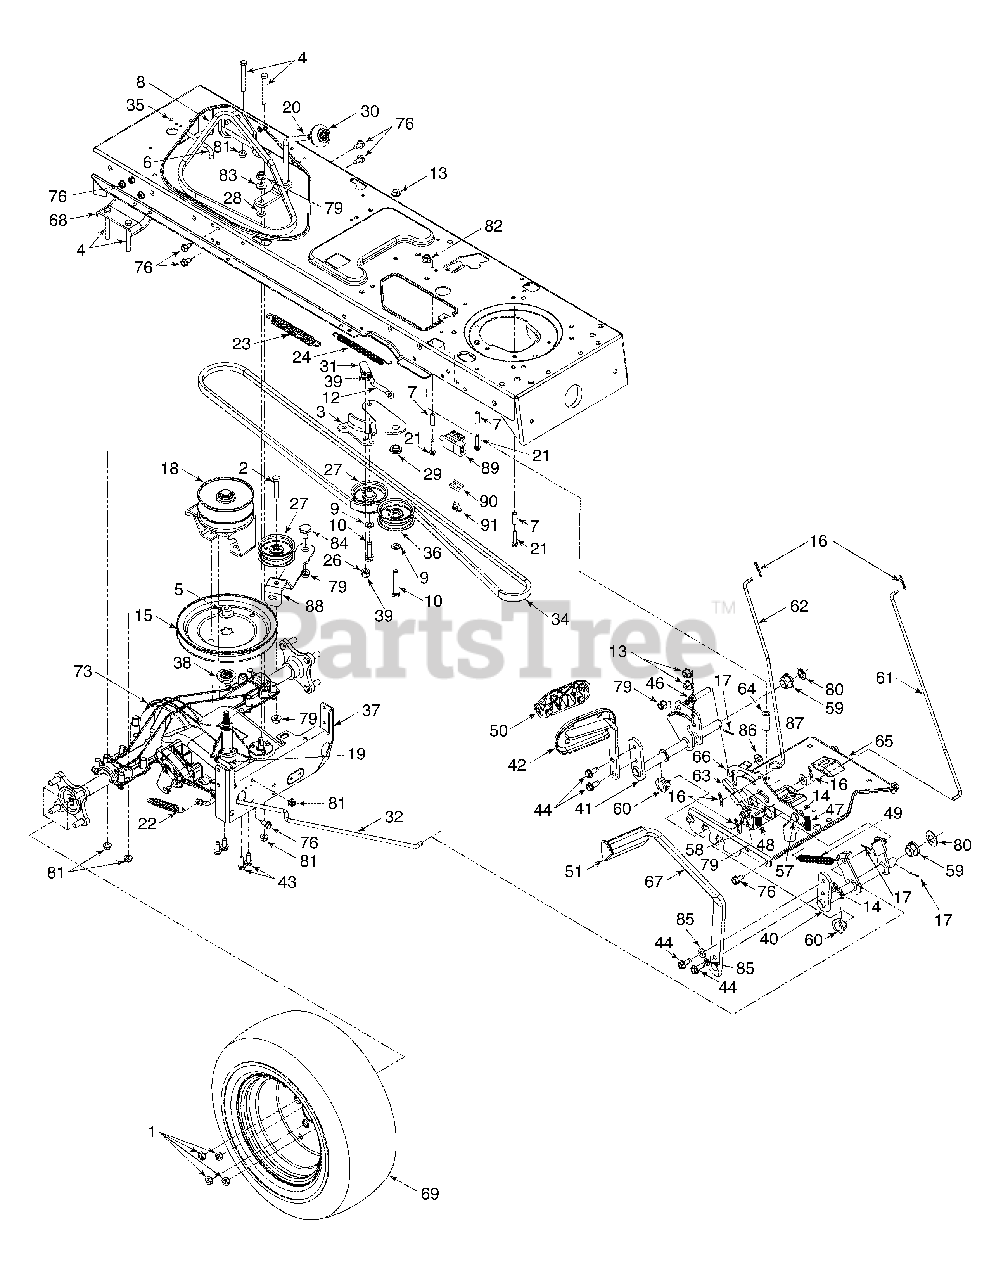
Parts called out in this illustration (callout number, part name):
1	Lug Nut, 7/16-14
2	Hex Screw 3/8-16 x 1.75
4	Hex Scr 5/16-18 x 2.75
5	Hex Flanged L-Nut 7/16-20 Gr. 2
6	Belt Guard Rod
7	Spacer .260 x .375 x 1.030 Lg.
8	Drive Belt
9	Flat Washer .40 ID x .812 OD x .135
10	Hex L-Wash HD Scr 3/8-16 x 1.5
12	Idler Adjustment Rod, 3/8
13	Hex. Flanged L-Nut 3/8-16 Gr. F
14	Hex Flange L-Nut 5/16-18
15	V-Pulley
16	Int. Cotter Pin .072 x 1.13" Lg.
17	Cotter Pin 3/32 dia x 1.00 Lg.
18	Variable Speed Pulley
19	Hex Bolt 5/16-18 x 1,50" Lg. Gr. 5
20	Shift Rod Assembly
21	Hex Bolt 1/4-20 x 1.25
22	Ext. Spring .59 OD x 4.00 Lg.
23	Extension Spring 6.12 Lg.
24	Extension Spring, .50 Dia. x 6.37
26	L-Wash 3/8 ID
27	Idler V-Pulley
28	Flat Washer .44 x .75 x .06
29	Shoulder Spacer
31	Drag Link Ball Joint
34	Variable-speed Belt
35	Thd Forming Scr. 1/4-20 x .75 Lg.
36	Flat Idler Pulley 2.75 OD
38	Pulley Hub 1/2 Spline
39	Hex Nut 3/8-24
43	Hex Wash Taptite 5/16-18 x .875
44	Hex Wash. Hd. Scr. 5/16-18 x .75 Lg.
46	Pin 3/8-16 x 2.68 Lg.
47	Compression Spring
48	Extension Spring, .50 OD x 1.41
49	Extension Spring, .50 Dia. x 6.37
50	AutoDrive Pedal Pad
51	Brake Pedal Pad
57	Shld. Scr .437 Dia x .162 Lg.
58	Shoulder Screw .500 x .25
59	Hex Flange Bearing .630 ID
60	Hex Flanged Bearing .628 ID
61	Cruise Control Rod
62	Brake Lock Control Rod
64	Spacer .385 ID x .635 OD x 1.54
66	AutoDrive Lockout Bracket
73	Two Speed Transmission Assembly
76	S-Tapp Scr 5/16-18 x .75
79	Hex Jam L-Nut 3/6-16 Gr. 5
80	Flat Washer .640 ID x 1.24 OD x .06
81	Flange Locknut 5/16-18 Gr. F, Nylon
82	Flange Lock-Nut 3/8-16 Gr. F, Nylon
83	Cupped Washer .375 ID x .870 OD x .063
84	Shoulder Screw .625 Dia. x .217
85	L-Wash 5/16 ID
86	Flat Washer .38 ID x .87 OD x .09
87	Flat Washer .385 ID x .87 OD x .06
89	Switch
90	Switch Plate
91	Hex Scr. AB #10-16 x .50
